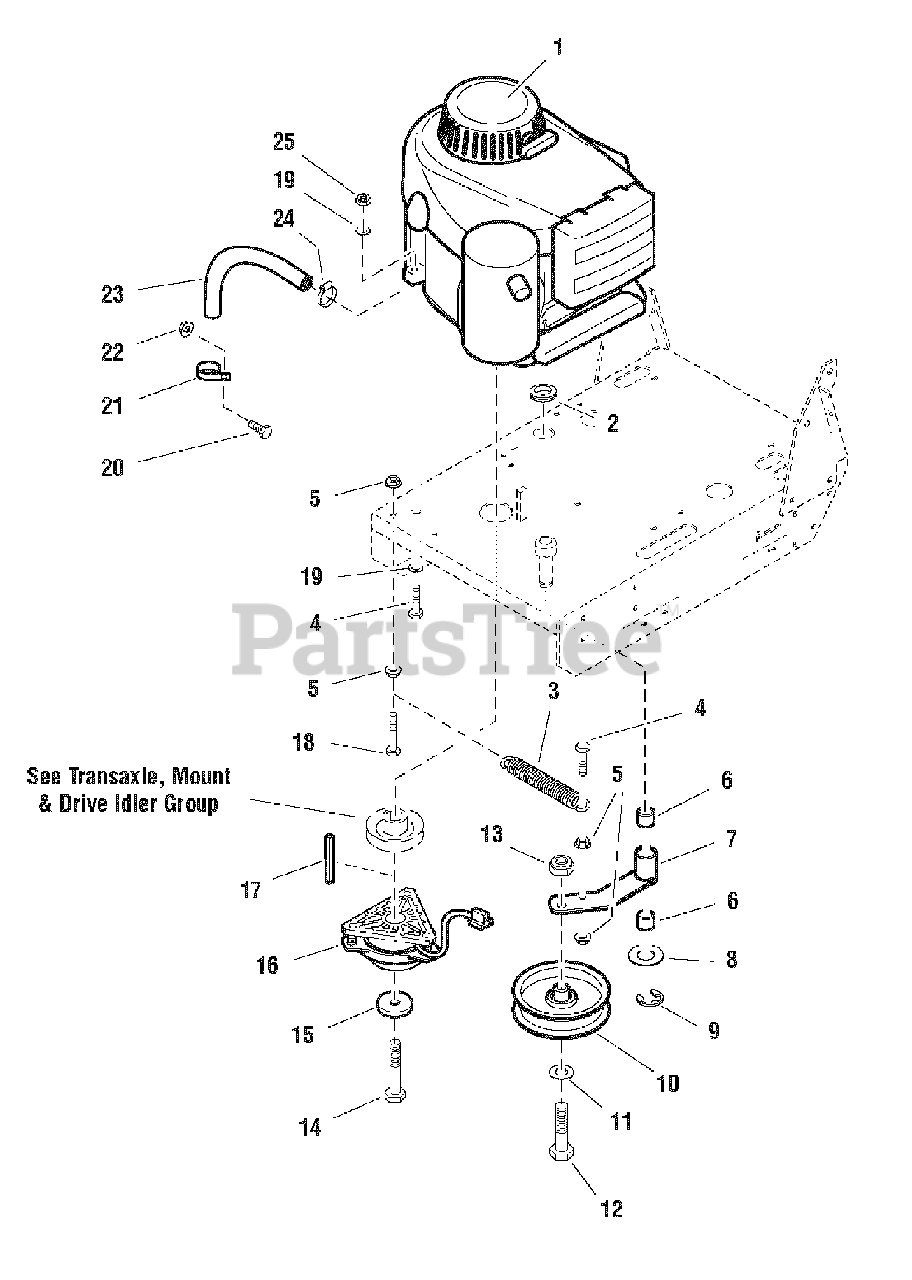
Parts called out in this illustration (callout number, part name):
2	GROMMET
3	SPRING, Extension
4	CAPSCREW, Hex Head, 5/16-18 x 1-1/2
5	NUT, Hex Serrated Flange, 5/16-18
6	BUSHING, Brass
7	DECK DRIVE IDLER ARM
8	WASHER, 3/4" SAE
9	C-CLIP
10	IDLER PULLEY
11	WASHER, 1/2
12	BOLT, 1/2-20 X 2-1/2" GD5 CZ
13	NUT, Hex, Nylon Lock, 1/2-20
14	CRANKSHAFT BOLT, 7/16 x 2-3/4
15	CLUTCH RETAINER
16	ELECTRIC CLUTCH
17	KEY, 1/4 Sq. x 2
18	CAPSCREW, Hex Head, 5/16-18 x 2-1/4
19	WASHER, 5/16
20	BOLT, 5/16-18 X 3/4 GD5
21	CLAMP
22	NUT, Hex Serrated Flange, 5/16-18
23	HOSE, 10-1/2 (oil drain)
24	CLAMP, #6 Hose
25	NUT, Hex Nylon Lock, 5/16-18
